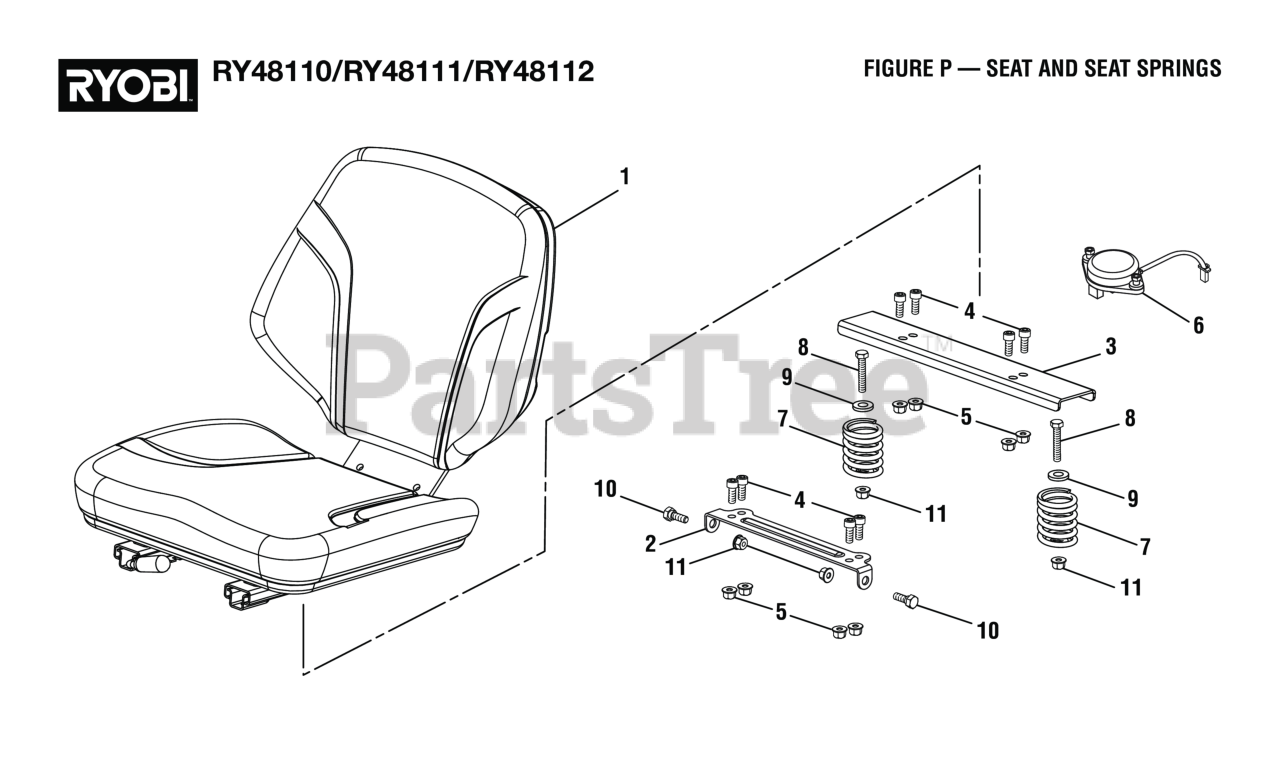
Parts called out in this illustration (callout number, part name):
2	Seat Base Plate
3	Seat Base Plate, Rear
4	Screw (M8 x 16 mm)
5	Lock Nut (M8)
6	Seat Switch
7	Seat Spring
8	Shoulder Bolt (M8 x 45 mm, Hex Flange Hd.)
9	Washer (OD 24 x ID8.4 x 2t)
10	Shoulder Bolt (M8 x 20 mm)
11	Flange Nut (M8) (For Drive Motor Controller V)
